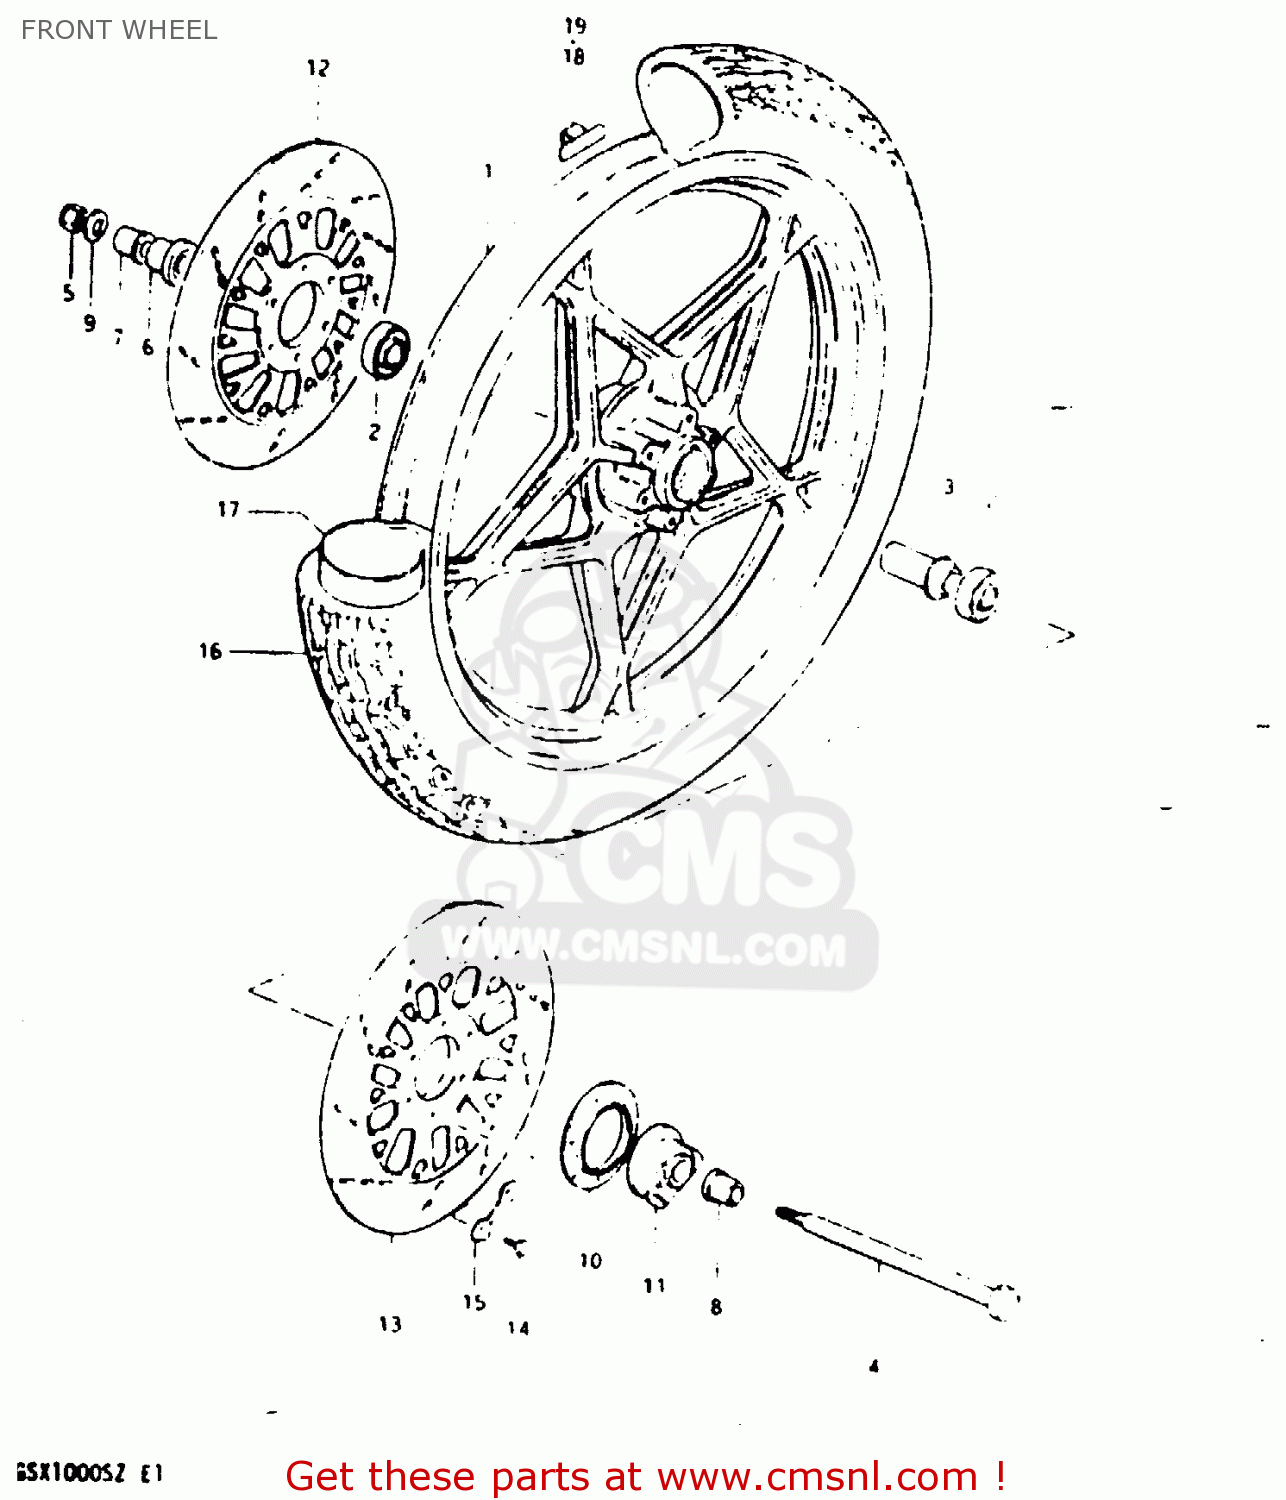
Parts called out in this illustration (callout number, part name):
1	WHEEL, FRONT (19*1.85)
2	BEARING
3	SPACER,FR HUB BEARING
4	AXLE,FR
5	NUT
6	SPACER,FR AXLE,R
7	SPACER,FR AXLE,R
8	SPACER,FR AXLE,L
9	WASHER
10	DUST SEAL,SPEEDOMETER GEAR BOX
11	BOX ASSEMBLY,SPEEDOMETER GEAR
12	DISC,FR BRAKE,R
13	DISC,FR BRAKE,L
14	BOLT(8X25)
15	WASHER
16	TIRE 3.50V19
17	TUBE,INNER
18	BALANCER,WHEEL
19	BALANCER,WHEEL (30G)
